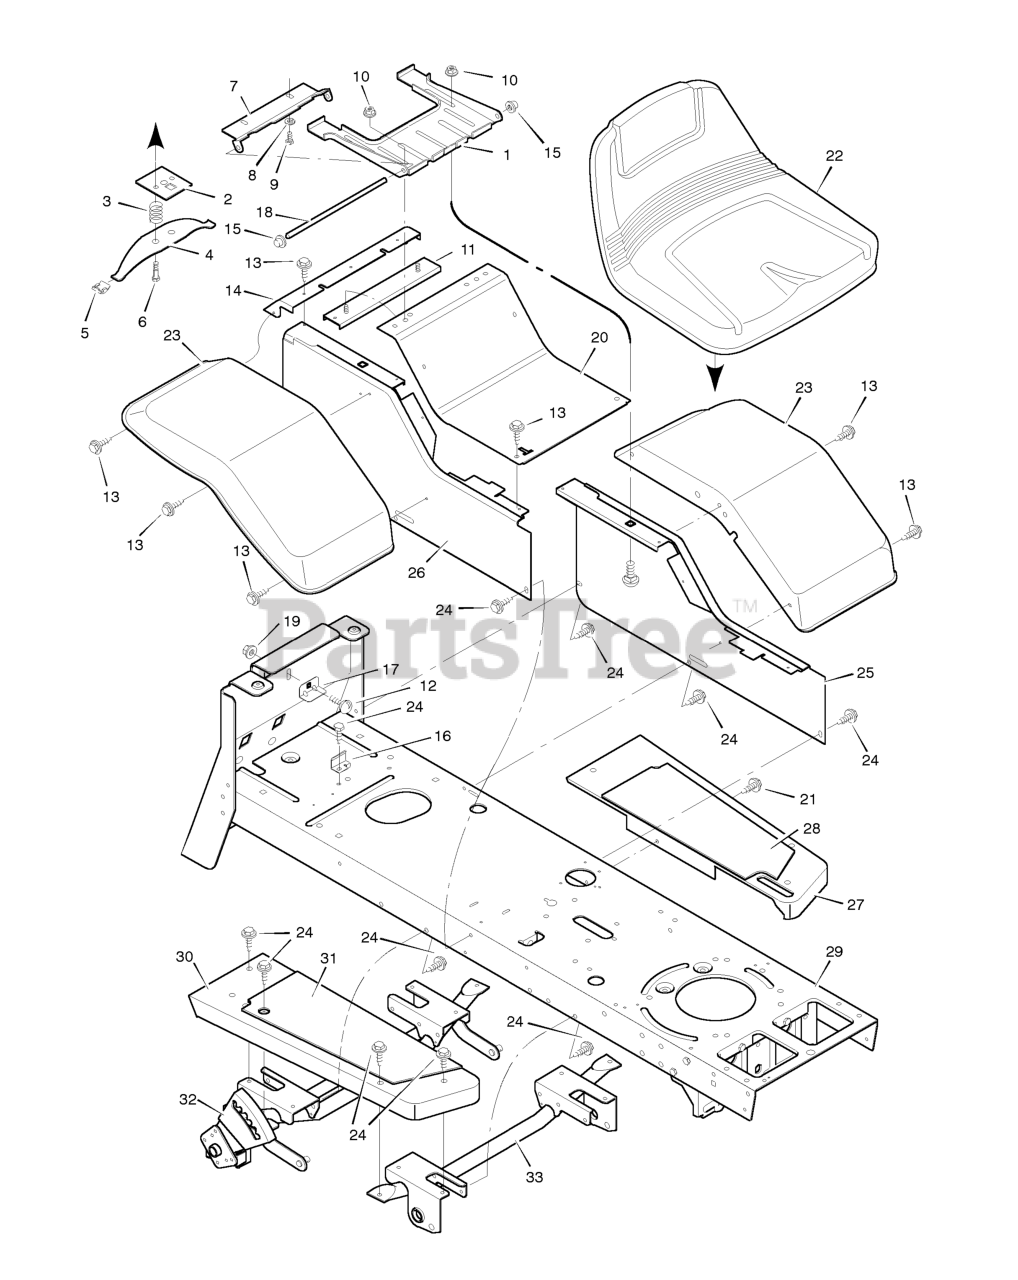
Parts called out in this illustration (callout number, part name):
1	Bracket, Seat
2	Plate Assembly, Switch
3	Spring, Compression
4	Spring, Seat
5	Glide, Spring
6	Bolt, Shoulder
7	Support, Seat
8	Lockwasher
9	Bolt, Hex
10	Locknut, Flange
11	Channel Assembly
12	Bolt, Carriage
14	Insert, Rear
15	Push On Cap
16	Support, Battery
17	Clamp, Battery
18	Rod, Pivot
19	Locknut
20	Panel, Top
21	Fastener, Panel
25	Panel, Left
26	Panel, Right
27	Running Board, Left
28	Mat, Left
29	Frame Channel
30	Running Board, Right
31	Mat, Right
32	Lifter and Support Assembly
33	Support Assembly, Front
